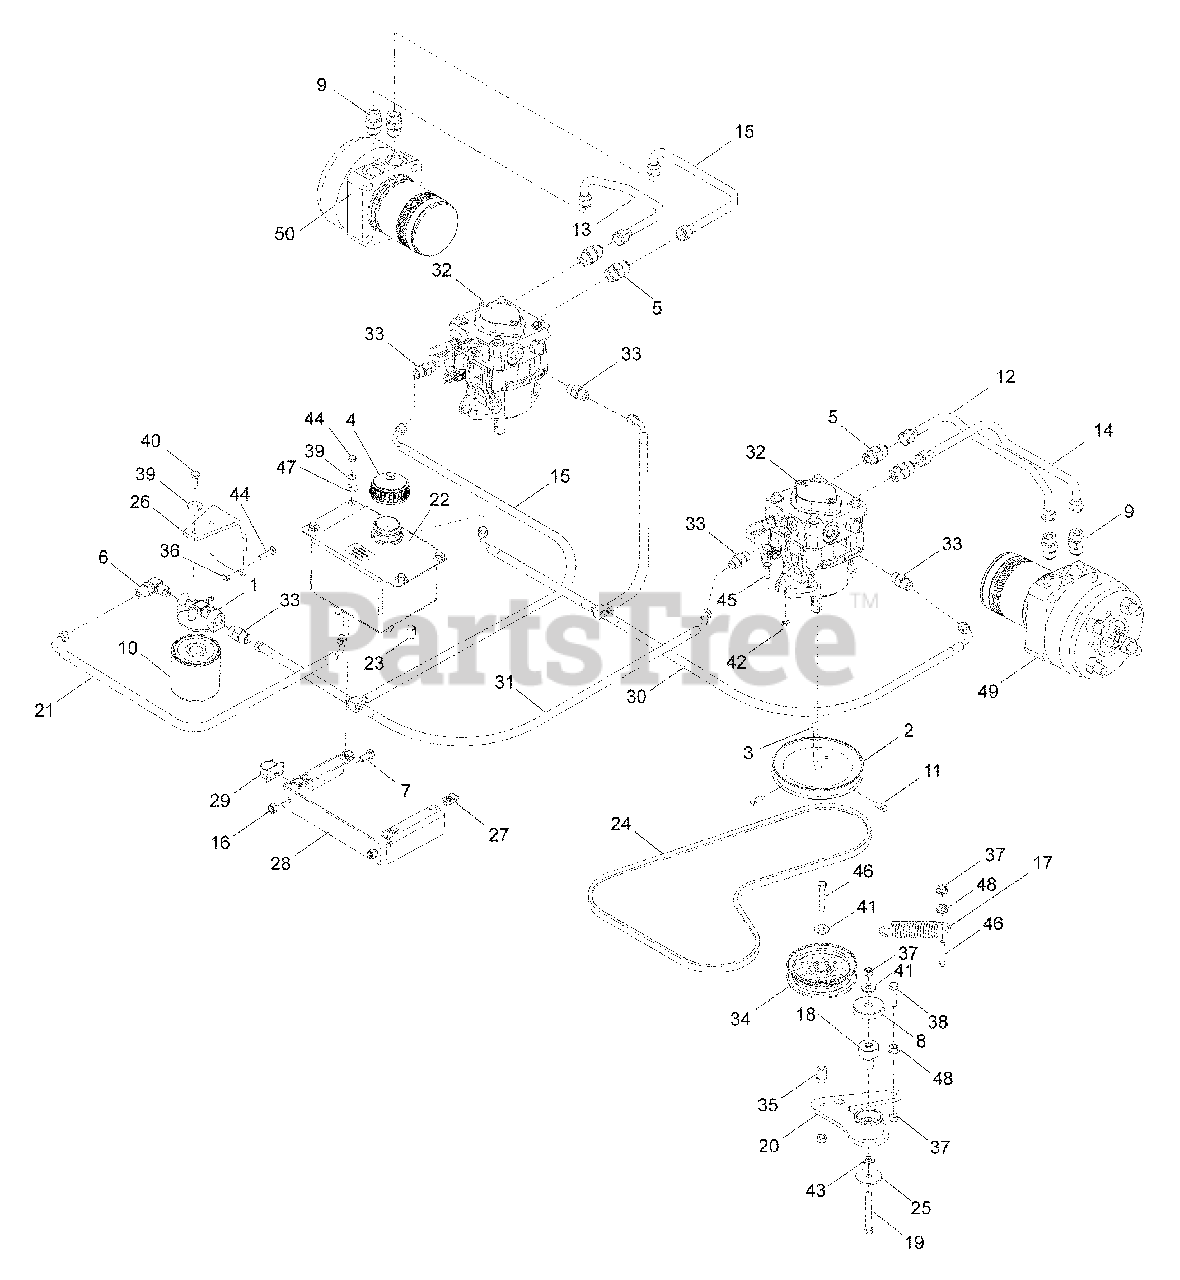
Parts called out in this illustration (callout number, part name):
1	FILTER HEAD
3	KEY, 5MM SQ x 30MM
4	CAP, HYDRO RESERVOIR
5	FITTING, F6400-8-8-0
6	FITTING, F6801-6-6-0
7	HCS 5/16-18 x ¾
8	SHIELD, DUST ½ ID
9	STRAIGHT FITTING
10	FILTER ELEMENT
11	SCREW 5/16-18 x 5/8
12	HYDRAULIC LINE
13	HYDRAULIC LINE
14	HYDRAULIC LINE
15	HYDRAULIC LINE
16	NUT 5/16-18 HEX NYLOC
17	SPRING, EXTENSION
18	BEARING, PIVOT
19	HCS 3/8-16 x 3
20	ARM, IDLER
24	BELT, PUMP
25	WASHER 3/8 SPECIAL
26	BRACKET, OIL FILTER
27	RETAINER, U TYPE
28	MOUNT, TANK
29	CLIP, WIRE
30	T ASSEMBLY
31	T ASSEMBLY
32	PUMP, 10CC w/RTN’S
33	FITTING, HYDRAULIC
34	PULLEY, IDLER
35	BUSHING, FLANGE IDLER
36	NUT ¼-20 HEX NYLOC
37	NUT 3/8-16 HEX NYLOC
38	HCS 3/8-16 x 1½
39	WASHER, ¼ SPLIT LOCK
40	HCS ¼-20 x 5/8
41	WASHER 3/8 FLAT STD
42	NUT 3/8-16 CENTERLOCK
43	WASHER 3/8 SAE FLT
44	HCS ¼-20 x ¾
45	HCS 3/8-16 x 1 WHIZLK
46	HCS 3/8-16 x 2
48	NUT 3/8-16 WHIZLK
49	WHEEL MOTOR iZC5221, iZC5223, iZ4821, iZ5223 VAN, iZ6125
